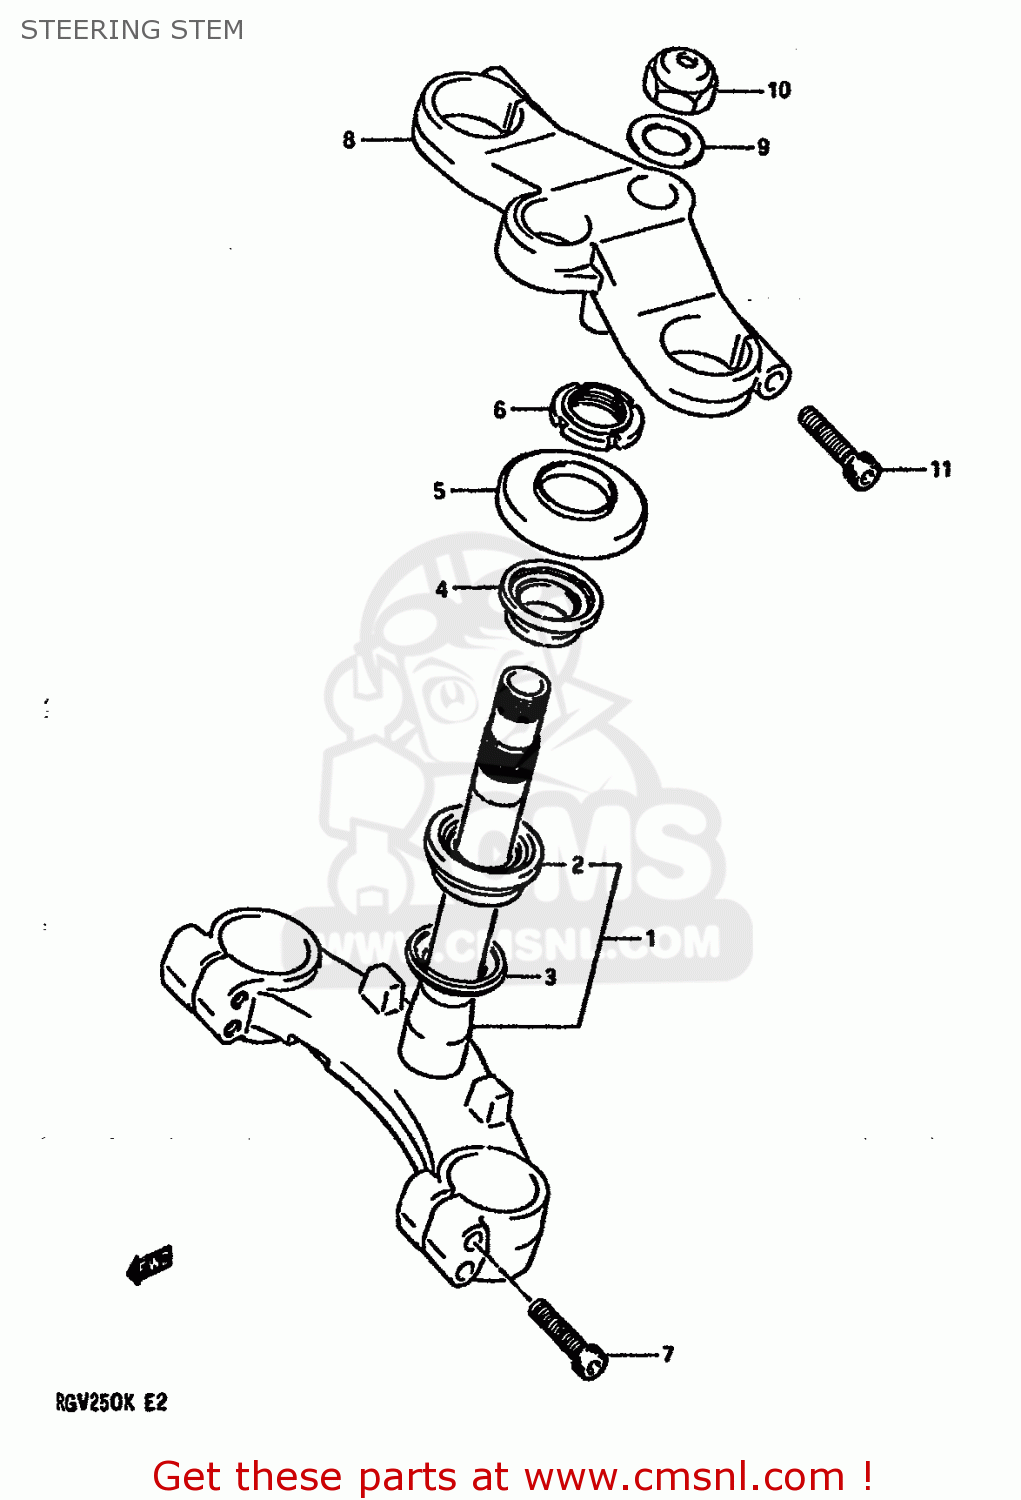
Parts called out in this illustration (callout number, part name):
1	STEM,STEERING
2	BEARING(30X55X17)
3	SEAL,STEERING LWR
4	BEARING(25X47X15)
5	SEAL OIL
6	NUT,STEERING STEM(25X44X10)
7	BOLT
8	STEM HEAD,STEERING
9	WASHER
10	NUT,STEM HEAD
11	BOLT
